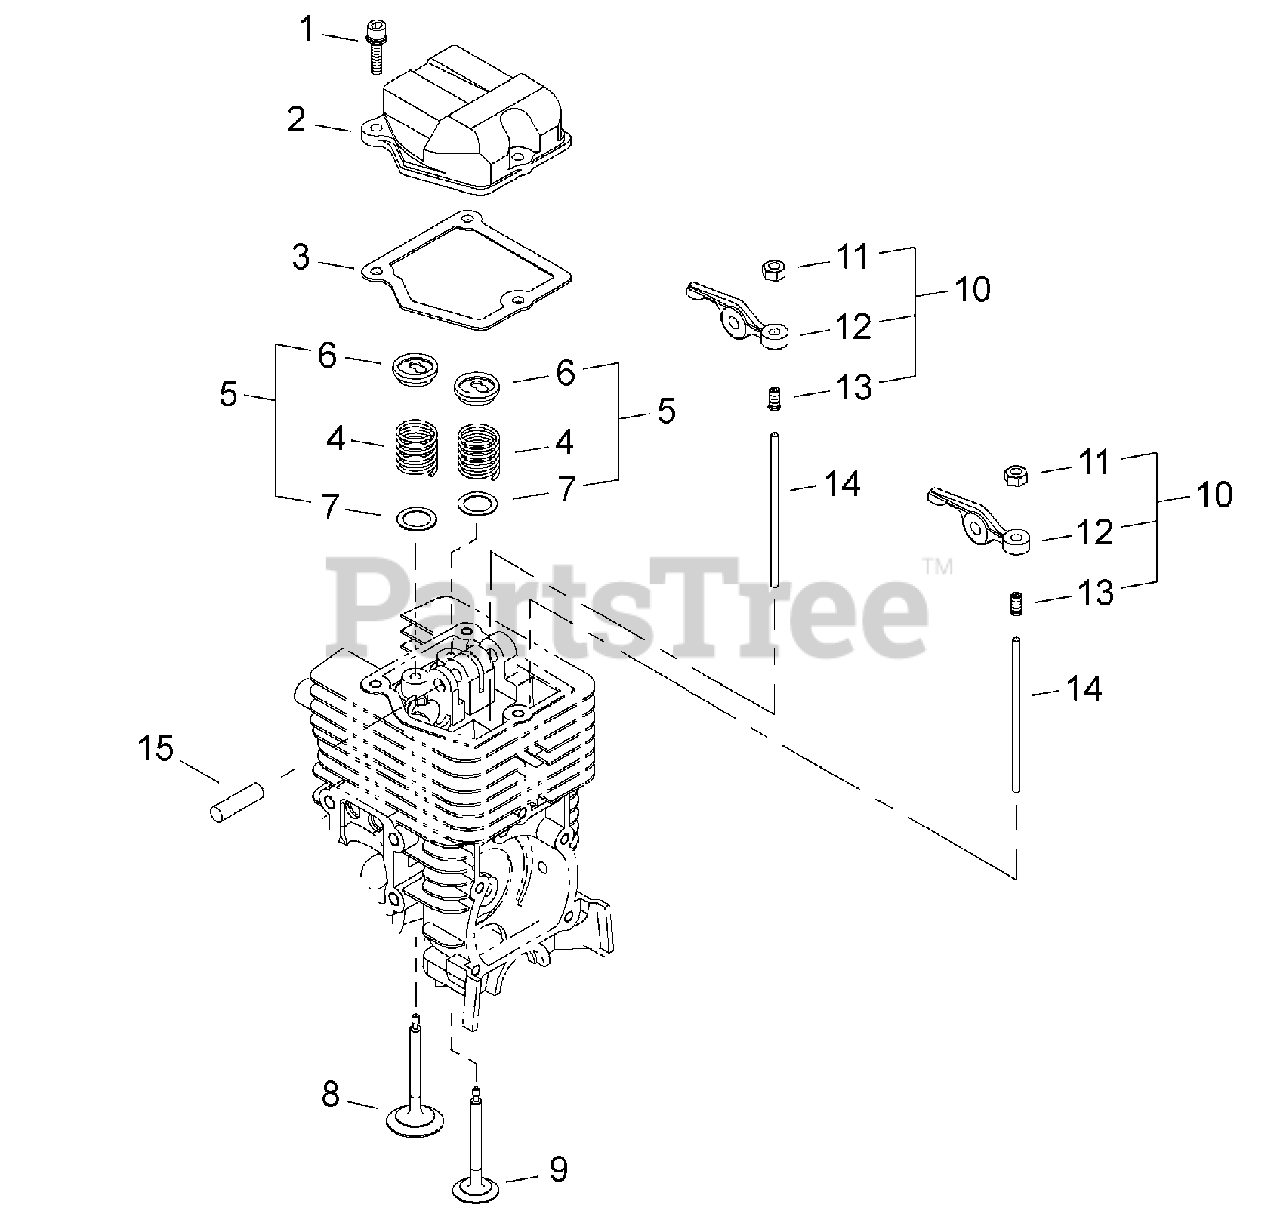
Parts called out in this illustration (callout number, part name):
1	SCREW - 4X12
2	COVER, ROCKER ARM
3	GASKET
4	SPRING, VALVE
5	VALVE RETAINER ASSY
6	RETAINER, VALVE
7	WASHER, VALVE - 9
8	VALVE, INTAKE
9	VALVE, EXHAUST
10	ROCKER ARM ASSY
11	LOCKNUT, ADJUSTER
12	ARM, ROCKER
13	SCREW, ADJUST
14	PUSHROD
15	SHAFT, ROCKER ARM - 5X31.8
